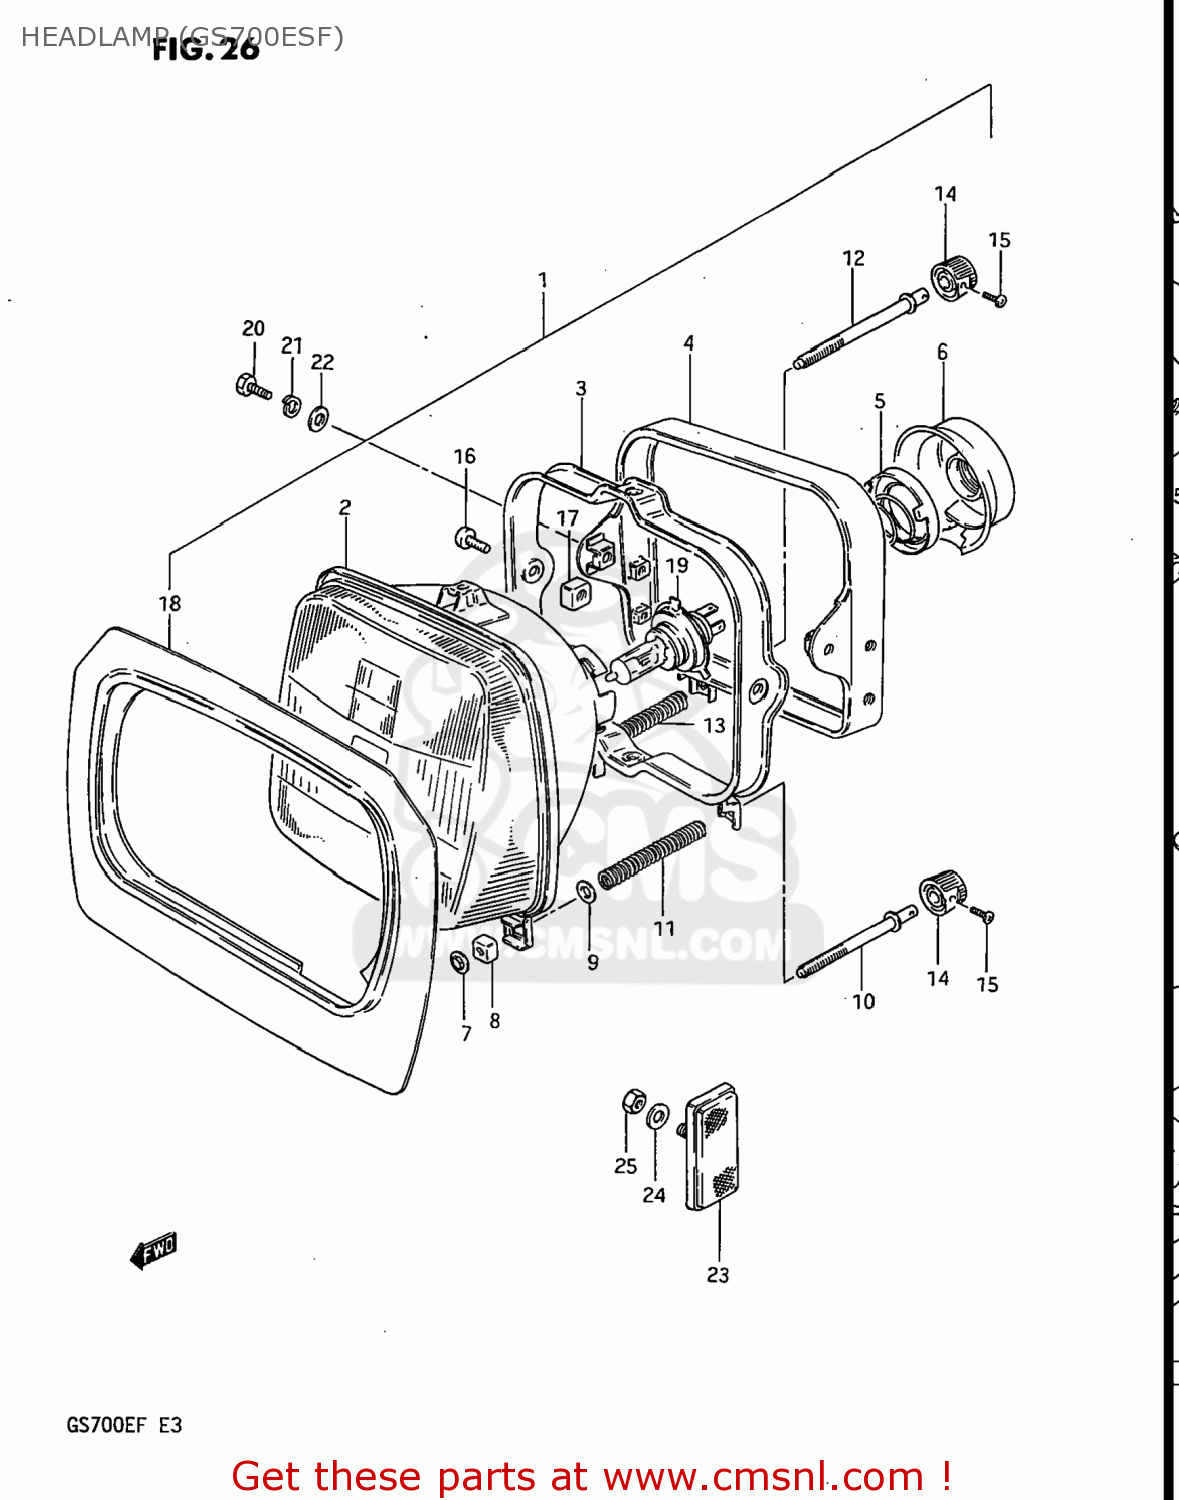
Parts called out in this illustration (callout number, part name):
1	LAMP ASSEMBLY,HEAD
2	LAMP UNIT
3	RING,MOUNTING
4	HOUSING,LAMP UNIT
5	HOLDER
6	COVER,HEADLAMP SOCKET
7	NUT,HEADLAMP ADJUSTER
8	NUT,HEADLAMP ADJUSTER
9	WASHER
10	SCREW,HEADLAMP ADJUST
11	SPRING
12	SCREW,ADJUSTING
13	SPRING
14	KNOB,ADJUSTER
15	SCREW
16	SCREW
17	NUT
18	SHADE
19	BULB(12V60/55W,H4)
20	BOLT,M6X1X20
21	WASHER,LOCK
22	WASHER, LOWER
23	REFLEX REFLECTOR,FR SIDE
24	WASHER,5MM
25	NUT ,5MM
